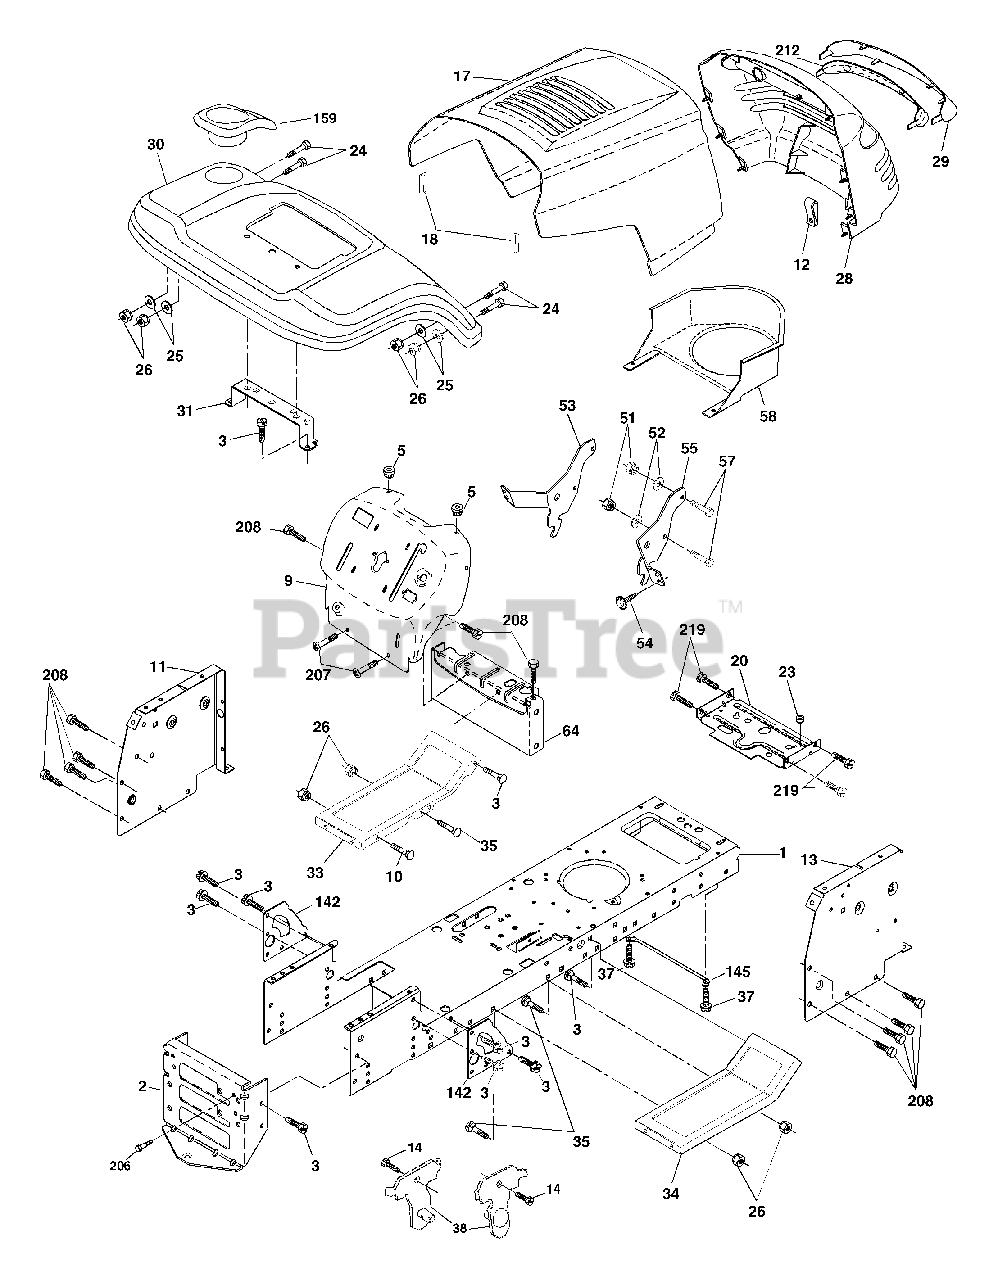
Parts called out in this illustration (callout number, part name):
1	Chassis stamping
2	Drawbar, 12 Ga.
3	Screw 3/8-16x3/4
5	Bumper Hood/Dash
9	Dash Slkscr
10	Bolt Carriage 3/8-16 x 1
11	Panel Dash Lh
12	Clip Tinnerman
13	Panel Dash Rh
14	Screw Thdrol 3/8-16 x 1/2
17	Hood LT/PL
18	Bumper Hood
20	Plate Mtg Battery Fuel Tank Fr
24	Bolt Fin Hex 3/8-16 Unc x 1 Gr. 5
25	Washer 13/32 X 13/16 X 12 Ga
26	Nut Lock Hex w/Ins. 3/8-16 Unc
28	Grille/Lens Asm
29	Lens
30	Fender
31	Bracket Fender
33	Footrest Pnt Lh
34	Footrest Pnt Rh
35	Bolt Rdhd Sht Sqnk 3/8-16 x 3/4
37	Screw Thdrol 6/16-18 x 1/2 TYT
38	Bracket Asm Pivot Mower Rear
51	Nut Lock w/Insert 1/4-20 Unc
52	Washer 9/32 x 7/8 x 16 Ga.
53	Bracket Grille Lh
54	Screw Hex Wsh 8-18 x 7/8
55	Bracket Grille Rh
57	Bolt Hex 1/4-20 x 3/4
58	Air Duct Engine P/L
64	Dash Lower STLT
142	Plate Reinforcement STLT
145	Rod Pivot Chassis/Hood
159	Cupholder Stlt Grey
206	Bolt Shoulder 5/16-18 TT
207	Screw Thdrol 5/16-18 x 1/2
208	Screw Thdrol 3/8-16 x 1/2
212	Insert Lens Reflective
219	Screw 5/16-18 x 3/4 Tap
